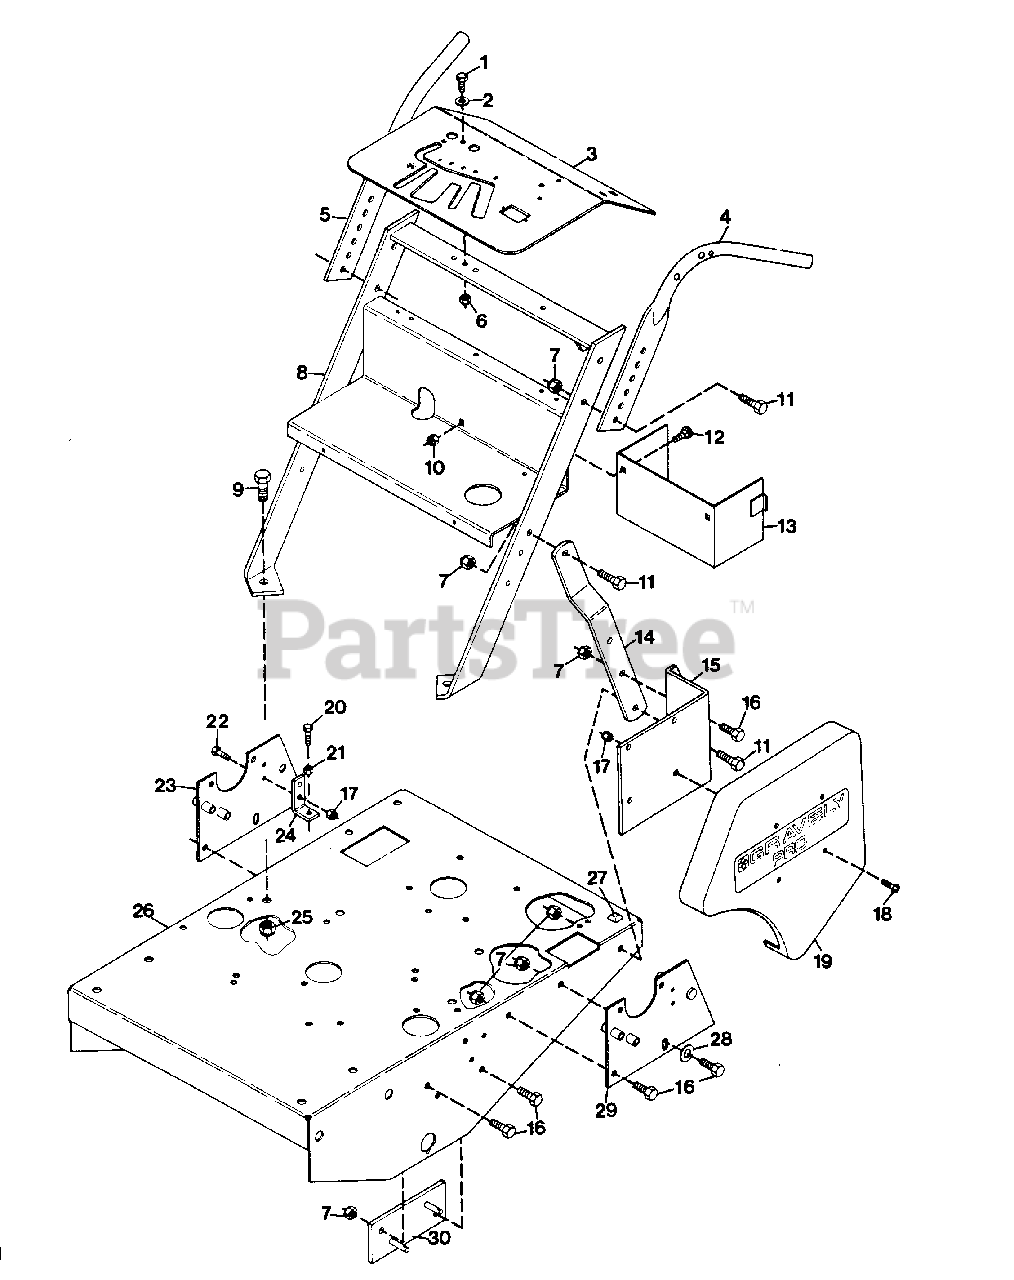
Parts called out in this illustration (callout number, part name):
1	BOLT, HEX 5/16-18X1.00
2	WASHER, FLAT .344X.688X.065
3	PLATE, SILK SCREEN
4	HANDLEBAR, L.H.
5	HANDLEBAR, R.H.
6	NUT, LOCK 5/16-18
7	NUT, LOCK 3/8-16
8	WELDMENT, HANDLEBAR SUPPORT
9	BOLT, HEX 1/2-13X1.25
10	NUT, LOCK 5/16-18
11	BOLT, HEX 3/8-16X1.25
12	BOLT, 5/16-18X.625 RD HD SQ NK
13	WELDMENT, BATTERY BOX
14	BRACE, HANDLEBAR SUPPORT
15	BRACKET, BELT GUARD L.H.
15	BRACKET, BELT GUARD R.H.
16	BOLT, HEX 3/8-16X1.00
17	NUT, LOCK 1/4-20
18	SCREW, MACH. 1/4-20X.625 RD HD
19	GUARD, BELT L.H.
19	GUARD, BELT R.H.
20	BOLT, HEX 1/4-20X1.00
21	NUT, HEX 1/4-20
22	BOLT, HEX 1/4-20X.625
23	WELDMENT, BEARING SUPPORT R.H.
24	BRACKET
25	NUT, LOCK 1/2-13
26	FRAME, PRO
27	STOP
28	WASHER, FLAT .406X.812X.065
29	WELDMENT, BEARING SUPPORT L.H.
30	WELDMENT, BRAKE PIN PLATE L.H.
30	WELDMENT, BRAKE PIN PLATE R.H.
